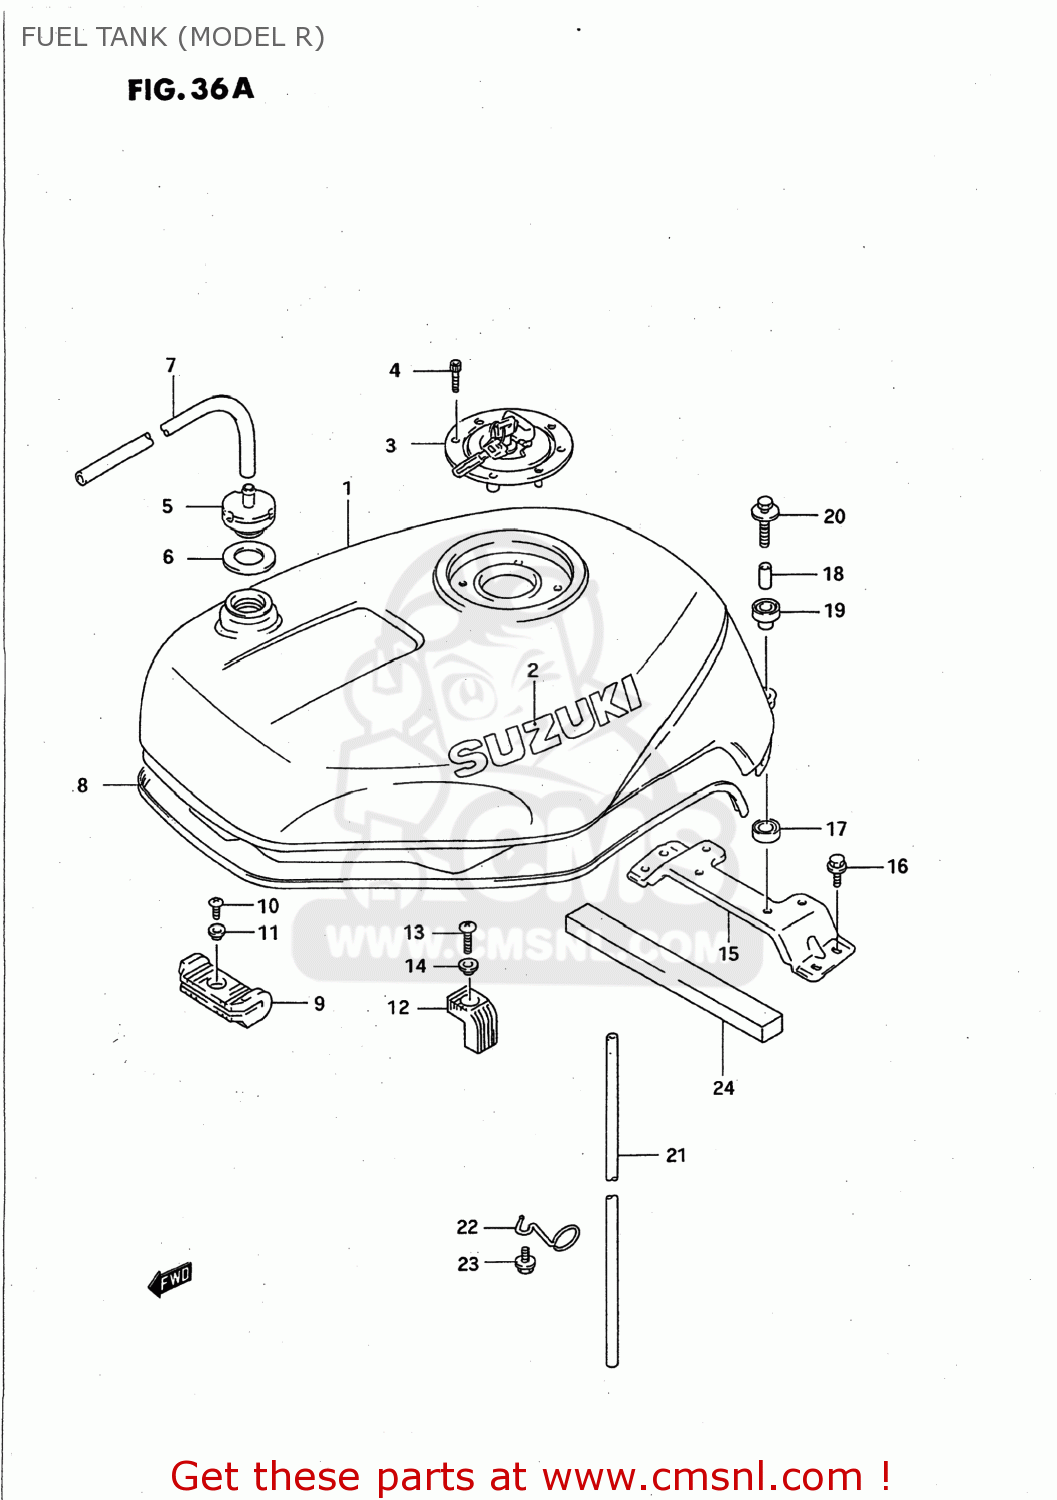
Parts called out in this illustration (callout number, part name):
1	TANK ASSEMBLY,FUEL
2	EMBLEM,FUEL TANK
3	CAP SET,FUEL TANK
4	BOLT(5X20)
5	PLUG,FUEL TANK BREATHER
6	GASKET 27X40X2.5 (NAS)
7	HOSE(5X8.2X600)
8	MOLDING,FUEL TANK
9	CUSHION,FUEL TANK FR
10	SCREW
11	WASHER
12	CUSHION,TANK SIDE
13	SCREW
14	WASHER
15	BRACKET,FUEL TANK,REAR
16	BOLT
17	CUSHION
18	SPACER
19	CUSHION
20	BOLT
21	HOSE (7X10.2X1000)
22	GUIDE,DRAIN HOSE
23	BOLT
24	CUSHION,AIR SEAL
